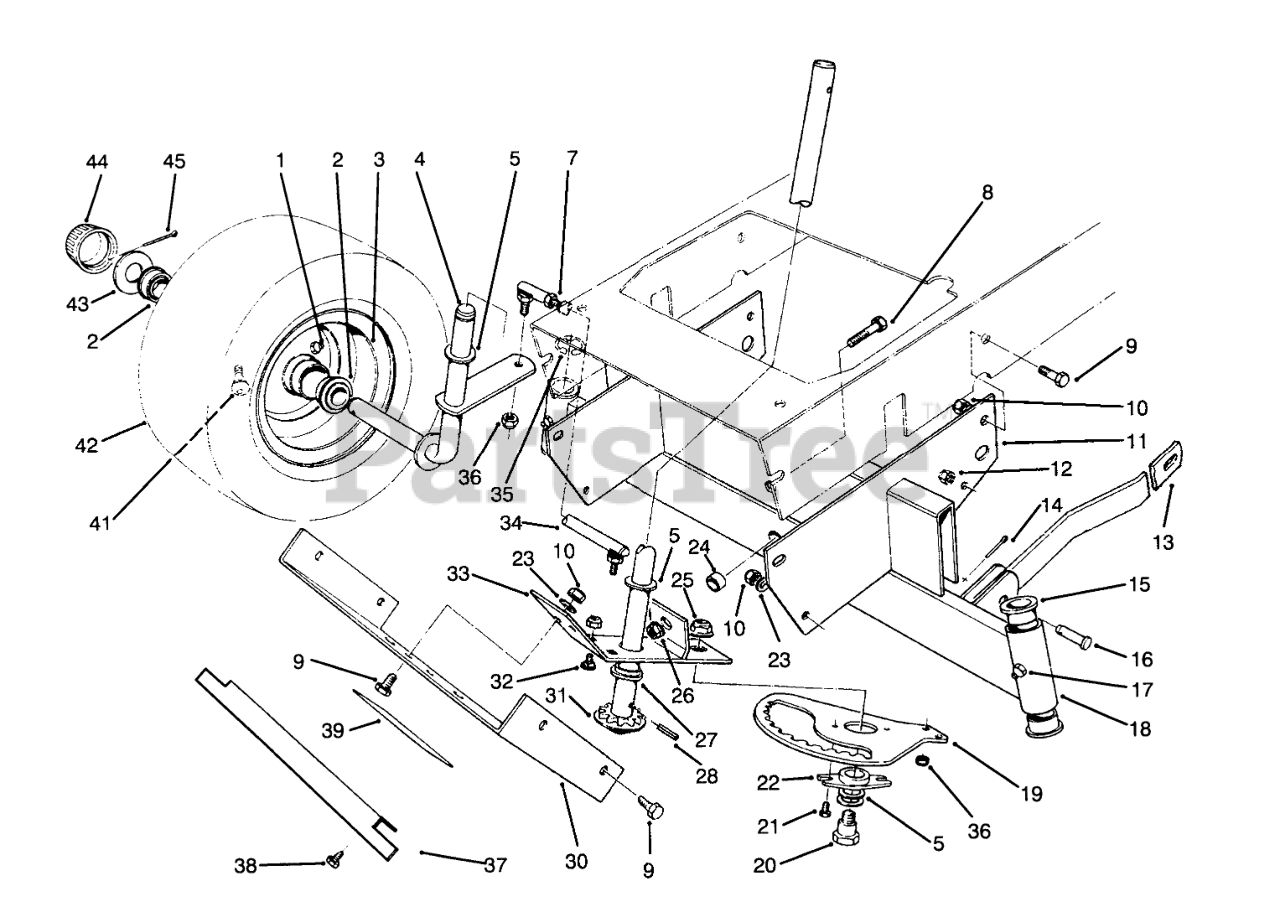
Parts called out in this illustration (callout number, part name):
1	FITTING-GREASE
2	Bearing
4	Spindle RH
5	WASHER-THRUST
7	NUT-JAM
8	SCREW-HH
9	SCREW-HH
10	NUT-LOCK, NI
11	Support
12	NUT-HEX
13	Arm-Suspension, Front
14	PIN-COTTER
15	BEARING-FLANGE
16	PIN-CLEVIS
17	GREASE FITTING
18	Axle-Front (Incl. Ref. #15 & 17)
19	Rack-Steering
21	SCREW-HWH
22	BUSHING-SECTOR
23	WASHER-PLAIN
24	SPACER-AXLE, FRONT
25	NUT-HF
26	NUT-HF
27	BEARING-FLANGE
28	PIN-ROLL, SLOTTED
30	Cover-Front
31	STRG SHAFT WA
32	SCREW-CARR
33	Bracket-Rack, Steering (Incl. Ref. #27)
34	Tie Rod-Adjustable (Incl. Ref. #7)
35	E-RING
36	NUT-LOCK
37	Guard-Front
38	SCREW-HWHTF
39	DECAL - IMPORTANT
41	STEM-VALVE
42	TIRE,PNEU.11X4.00X5
43	WASHER-PLAIN
44	CAP-HUB
45	PIN-COTTER
